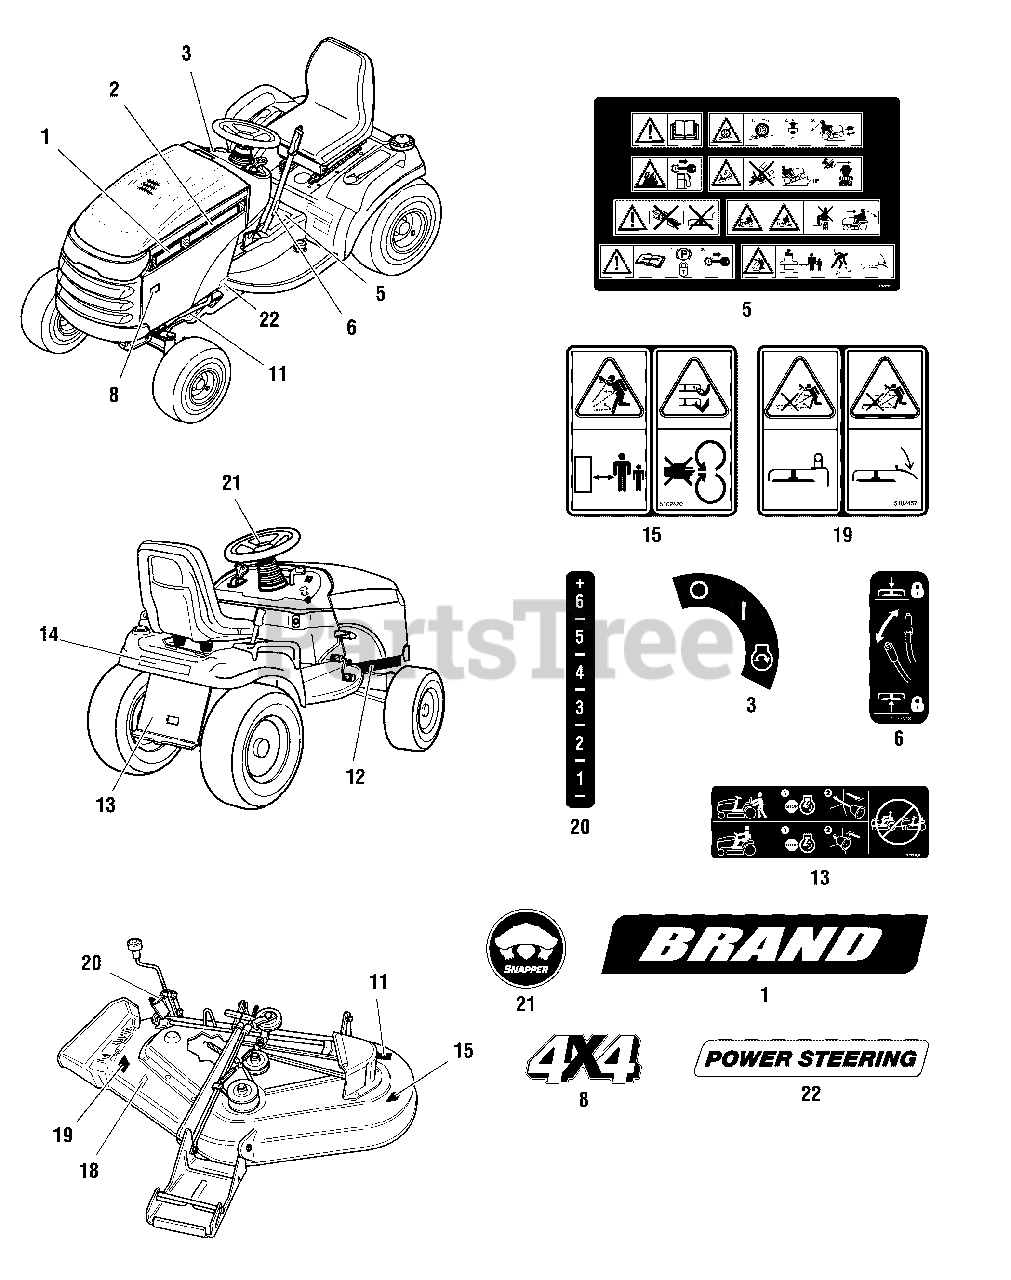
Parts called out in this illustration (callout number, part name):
1	DECAL, YT2452 24HP
2	DECAL, Snapper, LH & RH
3	DECAL, Ignition Switch Symbols, White/Black
5	DECAL, Tunnel, Export
6	DECAL, Lift Lever Symbols
8	DECAL, 4x4
11	DECAL, I.D. Plate
12	DECAL, Patent
13	DECAL, Transmission Release Valve
14	DECAL, Logo, Rear
15	DECAL, Danger, Mower Deck
18	DECAL, 52"
19	DECAL, Danger, Discharge, ANSI
20	DECAL, Height of Cut
21	DECAL, Steering Wheel Icon
22	DECAL, Power Steering
